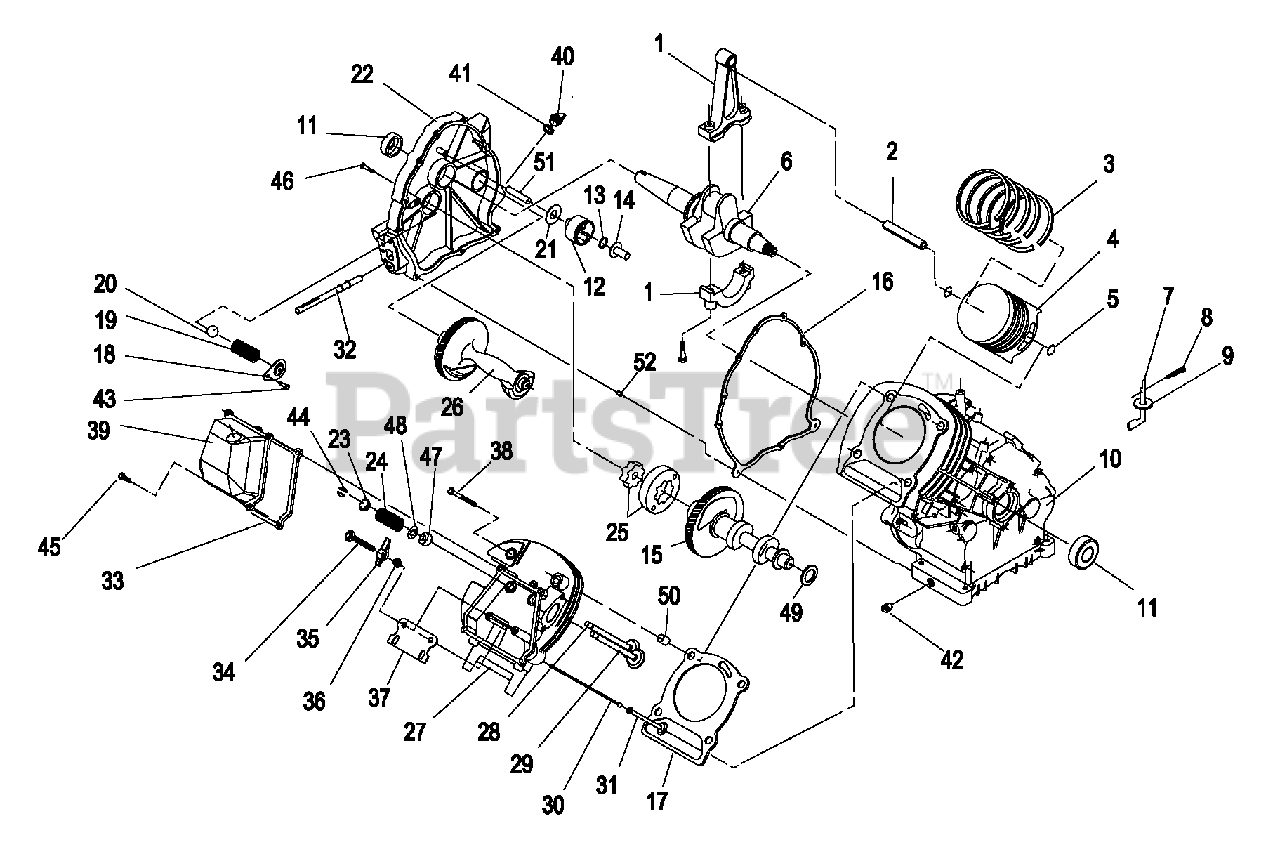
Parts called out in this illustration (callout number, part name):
1	ASSEMBLY, CONNECTING ROD
2	PIN, PISTON 020
3	RING SET, PISTON 090
4	PISTO N, FIAT TO P 090 COATED
5	RETAINER, PISTON PN 20
6	ASSEMBLY, CRANKSHAFTGH410 TAPER
7	A RM, GOVERNOR RC45
8	PIN, "R" GOVERNOR ARM
9	WASHE R, GOVERNOR ARM THRUST
10	C RANKCASE, SUBASSE MBLY WITH PLUG SGH410
11	SEAL,35 I.D.CRANKSHAFT
12	ASSEMBLY,GOVERNOR GEAR
13	C-RING, GOVERNOR GEAR RETAIN ER
14	SPOO L, GOVERNO R- M ACHINE
15	ASSEM BLY, CAMSHAFTS GEAR
16	GASKET, CRANKCASE
17	GASKET, HEAD 410
18	COVER, OIL P RESSURE REUEF
19	SPRING, OIL RELIEF360
20	BALL, DIA 11/32 PRESSURE RELIEF
21	WASHER, THRUST GOVERNOR GEAR
22	ASSEMBLY, COVER, GEARTOP CHECK / FILL
23	RETAINER, VALVE SPRING
24	VALVE SPRING LF
25	SET, GEROTOR 12THK
26	BALANCER
27	ASSEMBLY, CYUNDER HEAD SEATS & GUIDES
28	VALVE. EXHAUST
29	VALVE. INTAKE
30	PUSHROD 1749
31	TAPPET
32	ASSEMBLY, SCREENOIL PICK- UP
33	GASKET, ROCKER COVER 410
34	STUD, D20 PIVOT BALL
35	ROCKER ARM
36	NUT, JAM (ROCKER ARM)
37	PLATE, PUSH ROD GUIDE
38	SCREW, H HFL M10-1 .5 X 10 5
39	ASSEMBLY, ROCKER COVER BREATHER OHVI
40	PLUG, OILFLL PLASTIC
41	O-RING 178 1.0.x 24
42	PLUG, STANDARD PIPE 38 STEEL SQUARE HEAD
43	SCREW, TAPTITE M5-0 8 X 10 EP
43	SCREW HHFC S M6-1 X 12G8.8
44	KEEPER, VALVE SPRNG
46	SCREW, HHFC M8-1.25 X 42
47	SEAL, VALVE STEM 07
48	WASHER, VALVE SPRING
49	WASHER, LARGE SPRING
50	SLEEVE, DOWEL PIN 14 DIA.
51	SHAFT, GOVERNOR RC55
52	SLEEVE, DOWEL PI N12 DIA.
